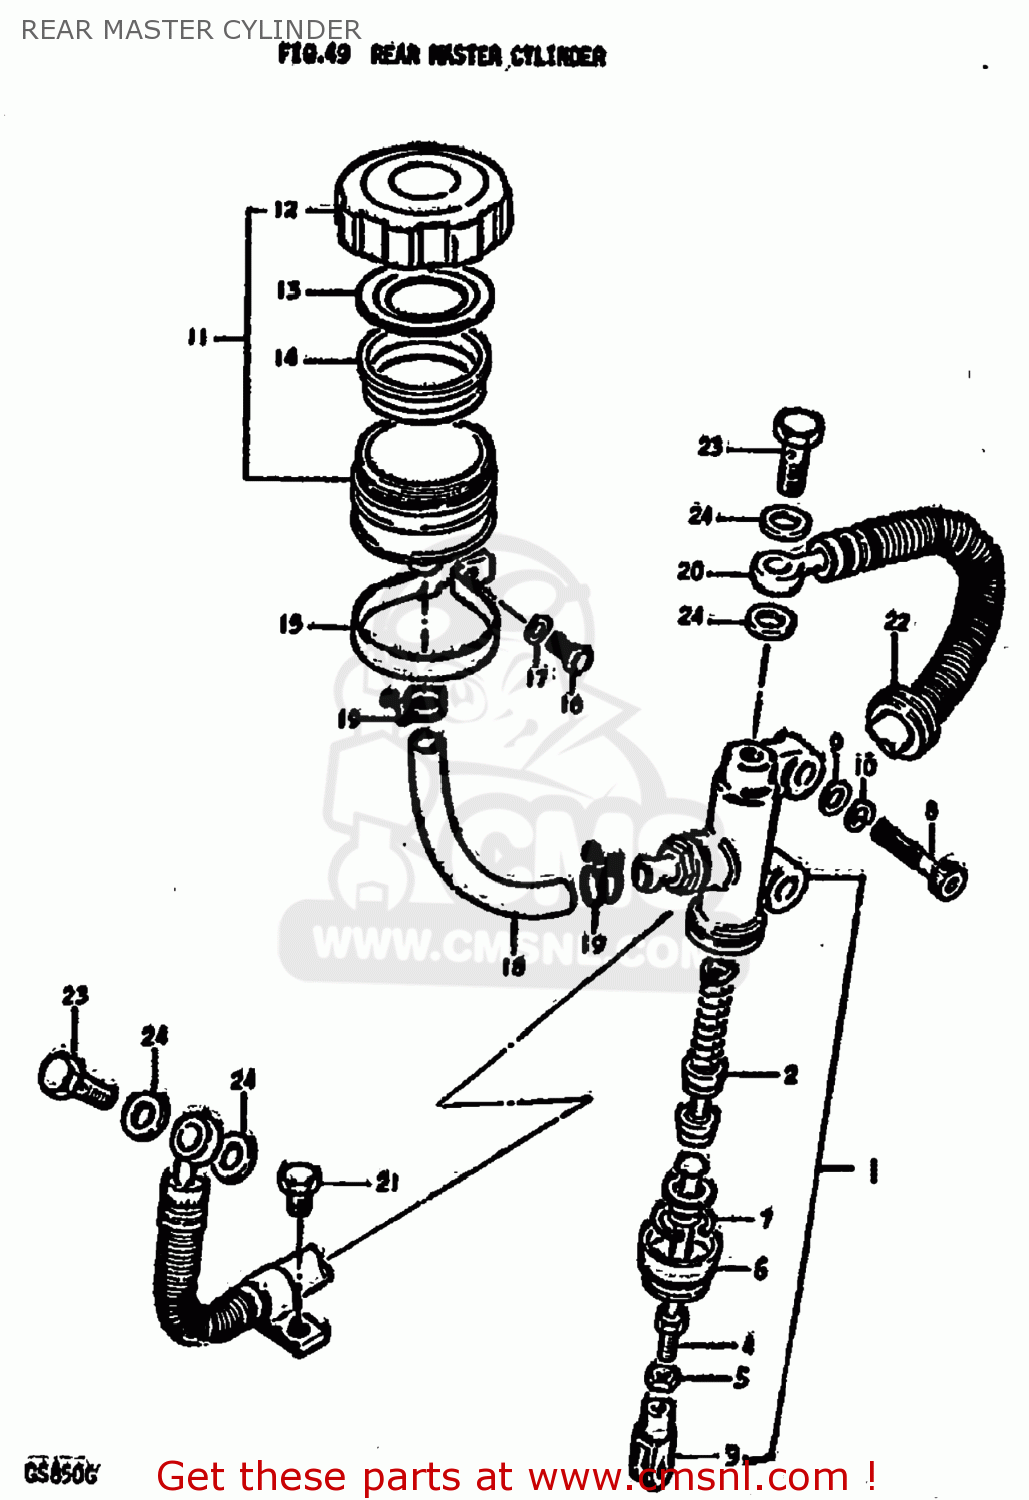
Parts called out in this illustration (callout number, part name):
1	CYLINDER ASSEMBLY,REAR MASTER
2	PISTON/CUP SET
3	YOKE
4	ROD,PUSH
5	NUT
6	BOOT
7	CIRCLIP
8	BOLT
9	WASHER
10	LOCK WASHER
11	TANK ASSEMBLY,RESERVOIR
12	CAP
13	PLATE,DIAPHRAGM
14	DIAPHRAGM
15	CLAMP
16	BOLT, UPPER
17	LOCK WASHER
18	HOSE,RESERVOIR TANK
19	CLAMP
20	HOSE,REAR BRAKE
21	BOLT
22	GROMMET
23	BOLT UNION
24	WASHER
